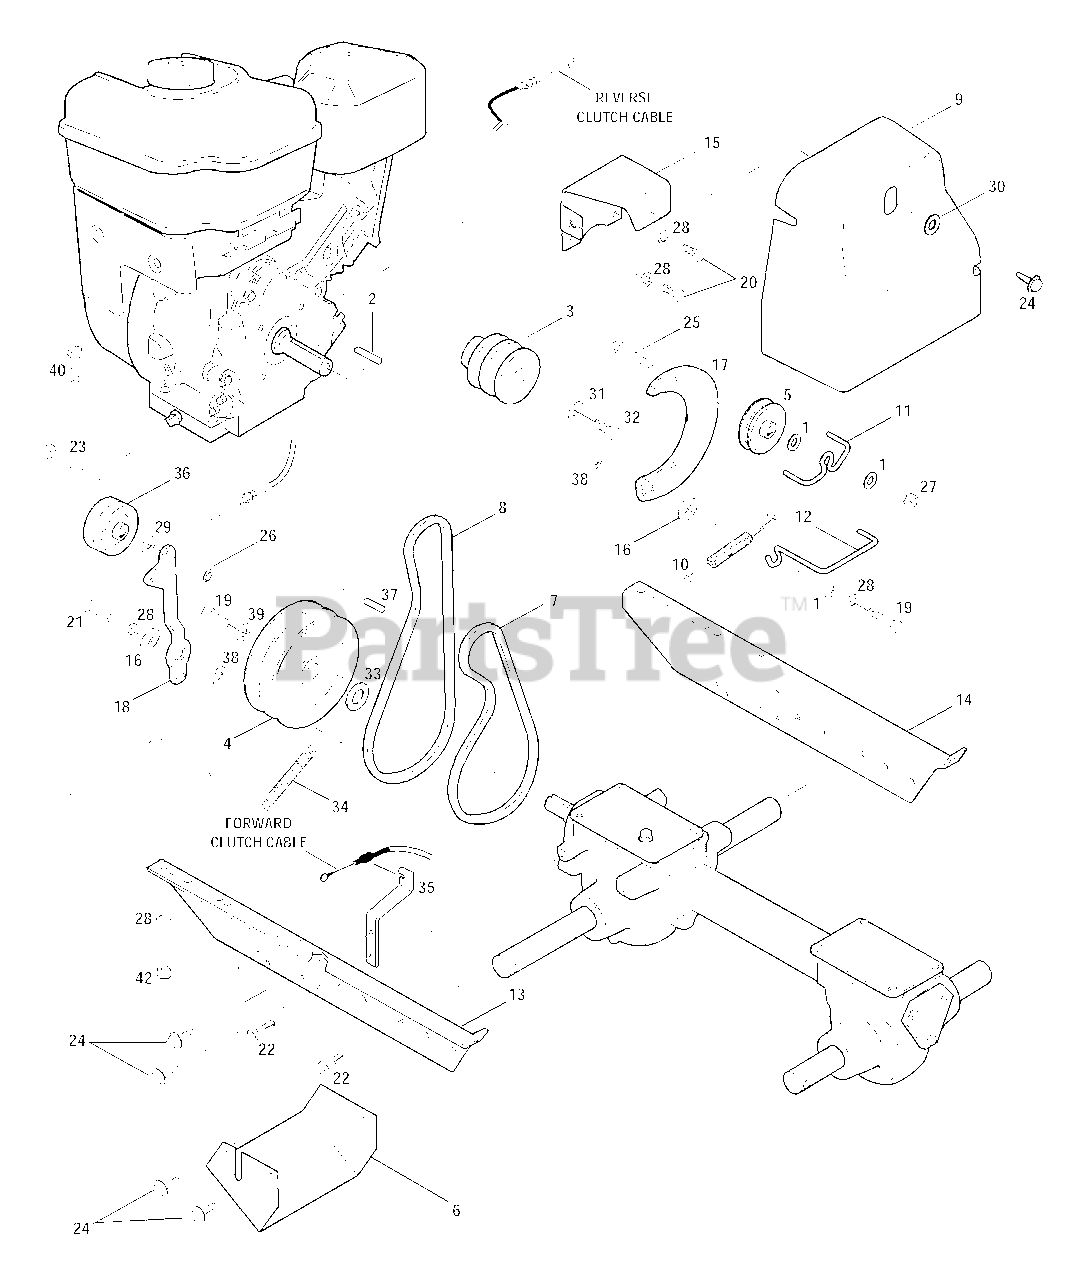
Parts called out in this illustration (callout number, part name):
1	Flat Washer, 5/16
2	Key, 3/16" x 1-1/2"
3	Pulley, Engine Drive
4	Transmission Pulley
5	Pulley, Reverse Idler
6	Guard, Belts/Pulleys
7	Forward Drive Belt
8	Reverse Drive Belt
9	Belt Cover
10	Reverse Return Spring
11	Belt Guide
12	Forward Belt Guide
13	Engine Bracket, Left
14	Engine Bracket, Right
15	Bracket, Belt Cover
16	Shoulder Washer
17	Reverse Idler Arm
18	Forward Idler Lever
19	Hex Hd. Screw, 5/16-24 x 1
20	Hex Hd. Screw, 5/16-24 x 5/8
21	Hex Hd. Screw, 5/16-18 x 1
22	Hex Hd. Screw, 5/16-18 x 5/8
23	Hex Hd. Screw, 3/8-16 x 1-1/2
24	Screw, Self-Tapping, 1/4-20 x 1/2
25	Hex Hd. Screw, 5/16-18 x 2
26	Lock Nut, 3/8-16
27	Lock Nut, 5/16-18
28	Lock Washer, 5/16
29	Flat Washer, 3/8
30	Flat Washer
31	Bell Washer
32	Hex Hd. Screw, 3/8-24 x 1.5, GR5
33	Support Washer
34	Forward Return Spring
35	Bracket, Cable Mounting
36	Forward Idler Pulley
37	Key, 3/16" x 1"
38	Flat Washer
39	Belleville Washer
40	Hex Screw, 5/16-18 x 2.25 Gr5
